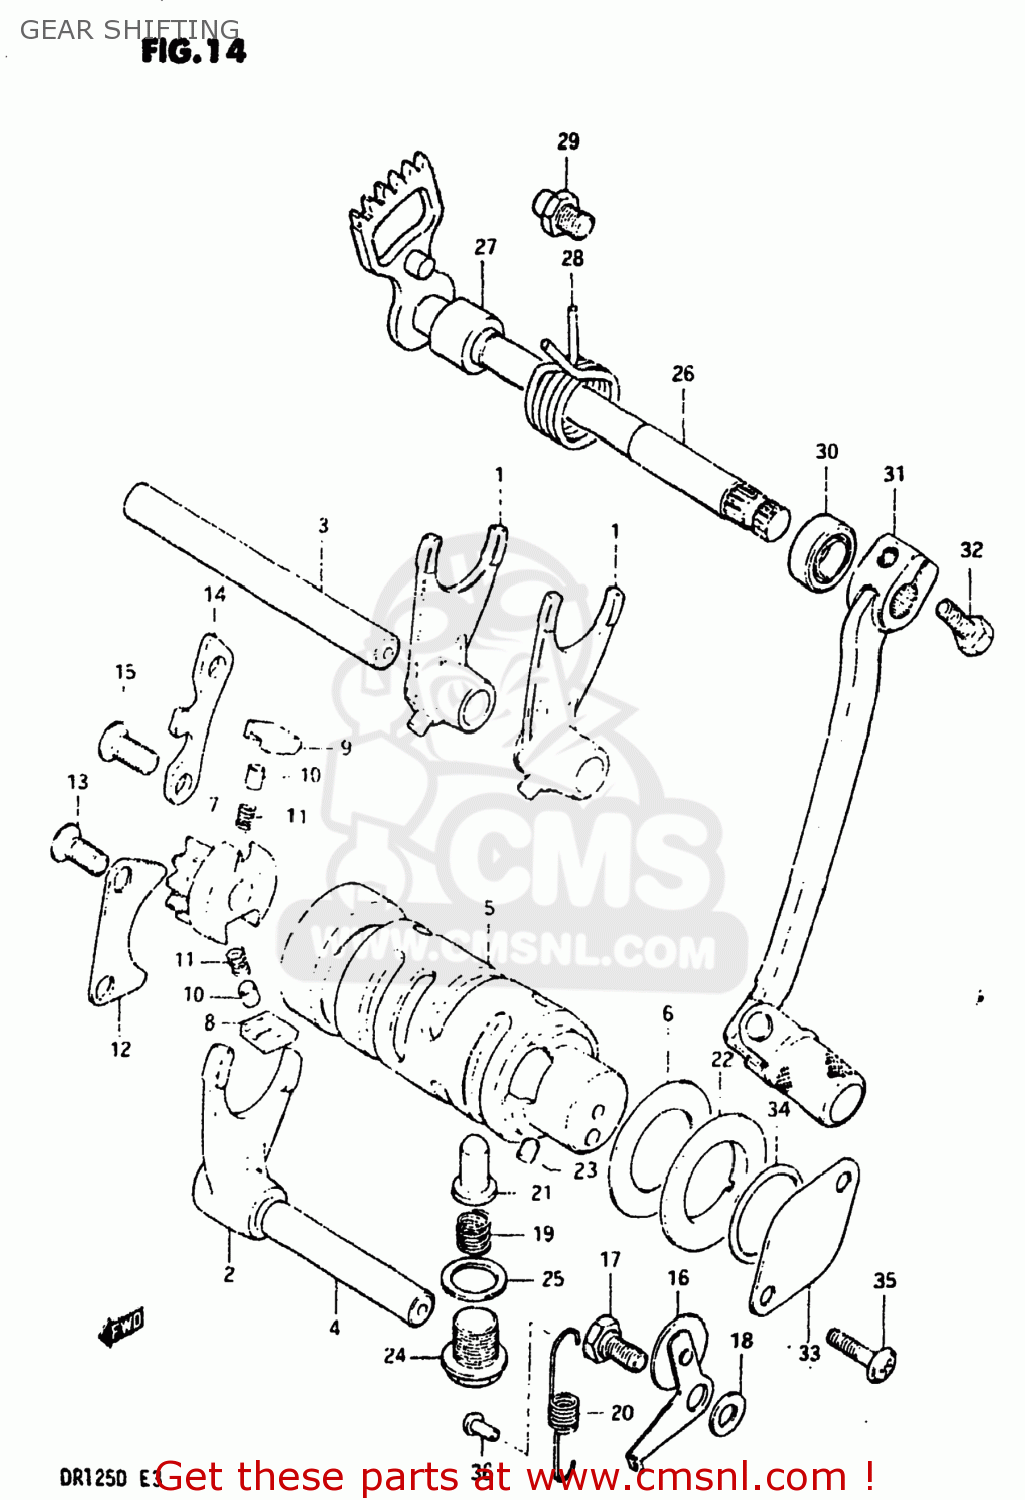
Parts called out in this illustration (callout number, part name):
1	FORK,GEAR SHIFT NO.1
2	FORK,GEAR SHIFT NO.3
3	SHAFT,GEAR SHIFT FORK
4	SHAFT,GEAR SHIFT FORK
5	CAM,GEAR SHIFT
6	WASHER,THRUST
7	RETAINER,GEAR SHIFT CAM
8	PAWL,GEAR SHIFT NO.1
9	PAWL,GEAR SHIFT NO.2
10	PIN(5X8)
11	SPRING
12	LIFTER,GEAR SHIFT PAWL
13	SCREW
14	GUIDE,GEAR SHIFT CAM
15	SCREW
16	STOPPER,GEAR SHIFTING
17	BOLT
18	WASHER
19	SPRING
20	SPRING
21	STOPPER,GEAR SHIFT CAM NO.2
22	PLATE,GEAR SHIFT CAM STOPPER
23	PIN 4X6
24	PLUG (14X12)
25	GASKET(14X19.2X2) (NAS)
26	SHAFT,GEAR SHIFT
27	SPACER(12X20X15.3)
28	SPRING
29	STOPPER,GEAR SHIFT CAM
30	OIL SEAL
31	LEVER ASSEMBLY,GEAR SHIFTING
32	BOLT
33	CAP,GEAR SHIFT CAM PIVOT
34	O-RING (D:2.4 ID:26.2)
35	SCREW
36	RIVET
